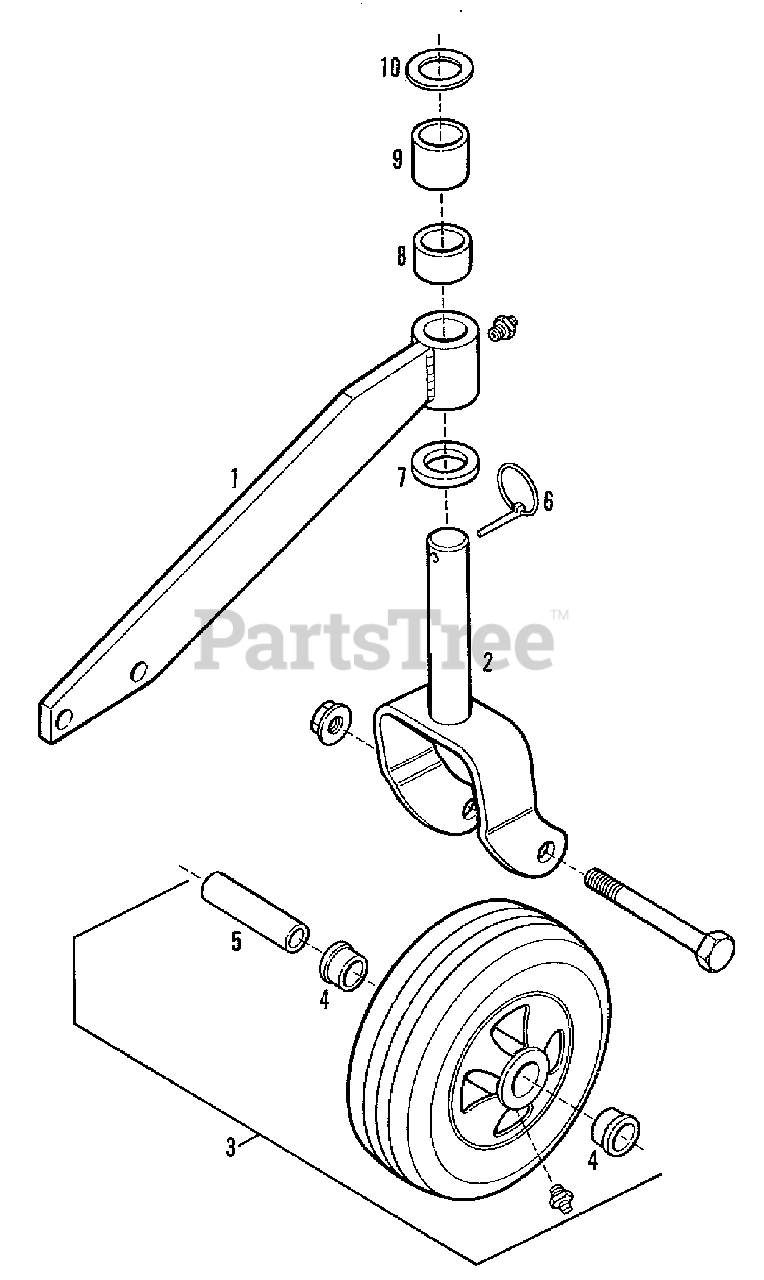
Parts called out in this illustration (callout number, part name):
1	ARM ASSEMBLY
1	FITTING, Lube, 1/4 Straight
1	CAPSCREW, 1/2NC x 1-3/4
1	LOCKWASHER, 1/2
2	FORK ASSEMBLY, Wheel
2	CAPSCREW, 1/2NC x 5
2	NUT, Lock, Flange, 1/2NC
3	WHEEL & TIRE ASSEMBLY (Pastic Rim)
3	WHEEL & TIRE ASSEMBLY (Steel Rim)
3	FITTING, Lube, 1/8 Straight
4	BEARING, Wheel Assembly, Iron (Use w/Plastic Rim Wheel)
4	BEARING, Wheel Assembly, Iron (Use w/Steel rim Wheel)
5	SLEEVE, Wheel Assembly (1/2" x 3/4" 3-3/8")
7	SPACER, Lower (1 x 1-5/16" x 1/2")
8	SPACER, Upper (1 x 1-5/16" x 1")
9	SPACER, Upper (1 x 1-5/16" x 1-1/2")
10	WASHER, Plain, 1-1/64" x 1-5/8" x 12 Ga.
